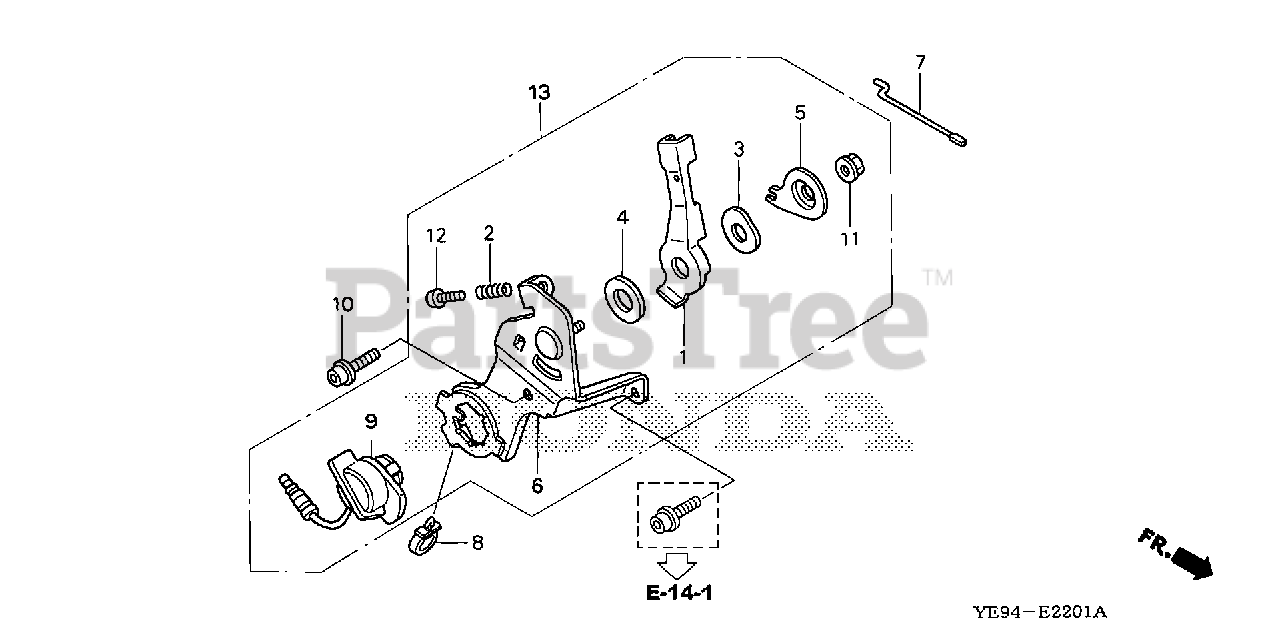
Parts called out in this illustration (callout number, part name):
1	LEVER, CONTROL
2	SPRING, CONTROL ADJUSTING
3	SPRING, LEVER
4	SPACER, CONTROL LEVER
5	WASHER, CONTROL LEVER
6	BASE, CONTROL
7	ROD, THROTTLE
8	CLIP, IGNITION WIRE (8MM)
9	SWITCH ASSY., ENGINE STOP
10	BOLT, SOCKET (5X10)
11	NUT, SELF-LOCK (6MM)
12	SCREW, PAN (5X25)
13	CONTROL ASSY.
